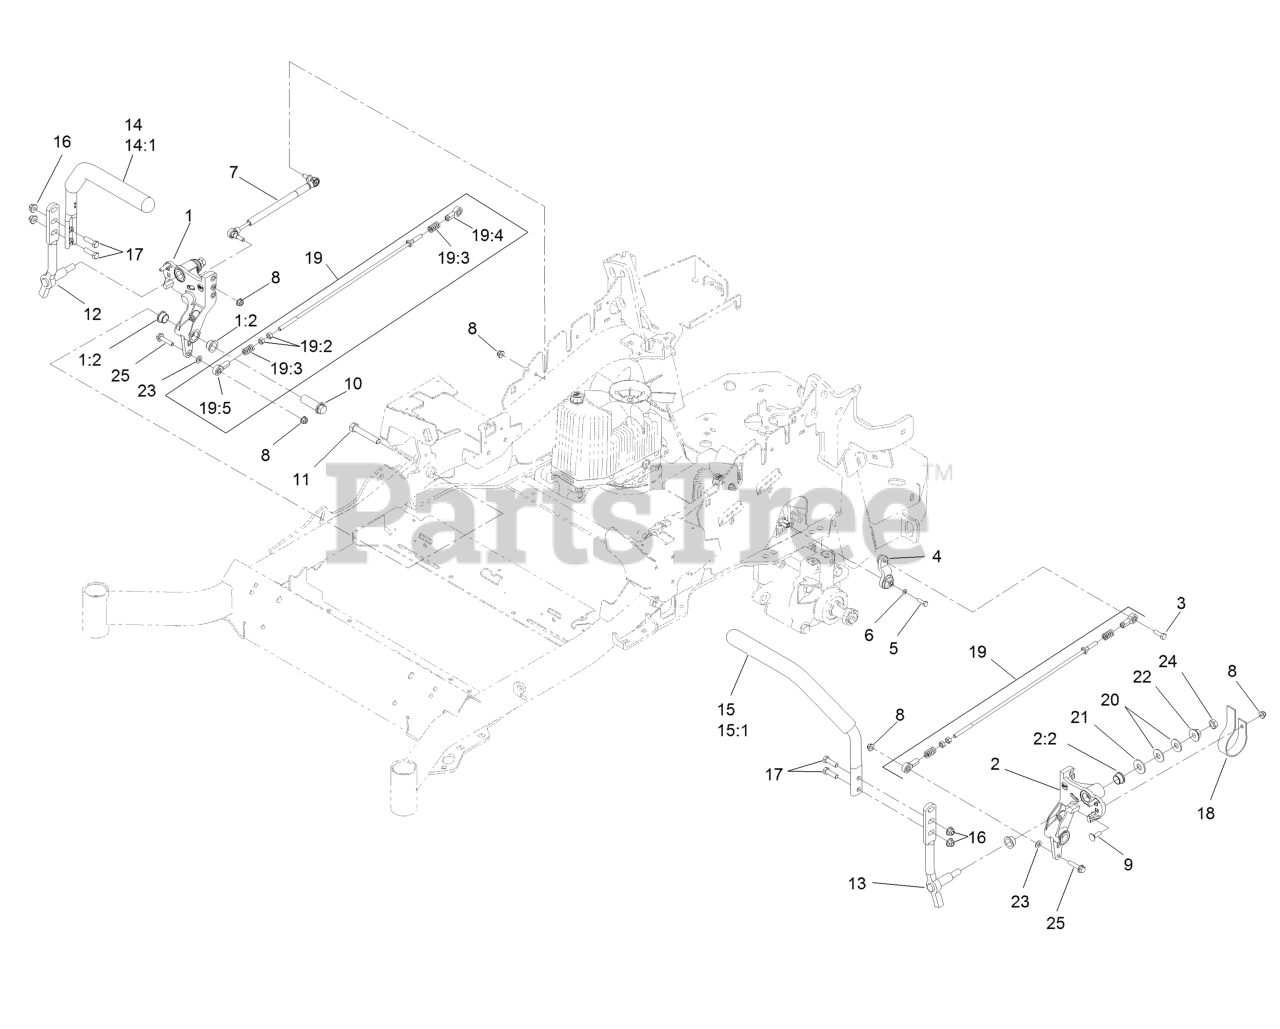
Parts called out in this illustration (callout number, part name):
1	RH MOTION CONTROL AND BUSHING ASM
1:2	BUSHING-FLANGE
2	LH MOTION CONTROL AND BUSHING ASM
2:2	BUSHING-FLANGE
3	SCREW-HH, THREAD LOCKING
4	ARM-CONTROL, PUMP
5	SCREW-HH
6	WASHER-SPRING
7	DAMPER-CONTROL, MOTION
8	NUT-HF, NI
9	BOLT-CARR
10	HUB-THREADED
11	SCREW-HH
12	LEVER-CONTROL MOTION, RH
13	LEVER-CONTROL MOTION, LH
14	RH STEERING HANDLE ASM
14:1	GRIP-LEVER, CONTROL
15	LH STEERING HANDLE ASM
15:1	GRIP-LEVER, CONTROL
16	NUT-HF, NI
17	SCREW-HH
18	SPRING-LEAF
19	FRONT PUMP LINKAGE ASM
19:2	NUT-HEX
19:3	SPRING-COMPRESSION
19:4	BALLJOINT-LH
19:5	BALLJOINT-RH
20	WASHER-SPRING
21	WASHER-FLAT
23	WASHER-PLAIN
24	NUT-JAM
25	SCREW-HHF
